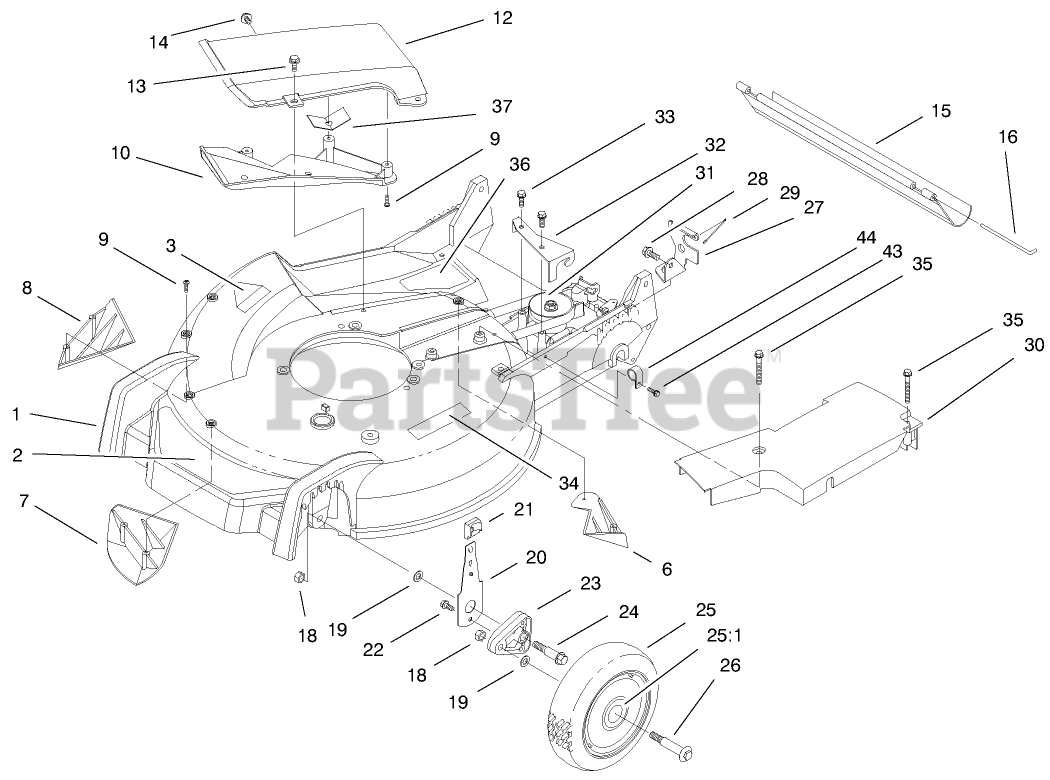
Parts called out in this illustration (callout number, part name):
2	DECAL - DECK
3	DECAL-DANGER
6	KICKER-REAR
7	KICKER-FRONT
8	KICKER-RH
9	SCREW-PPH
10	Deflector-Recycler
11	Guard-Cover
13	SCREW-HWH
14	SCREW AND WASHER ASM
16	ROD-SHIELD
18	NUT-LOCK
19	WASHER
20	FRONT SPRING ARM ASM
21	KNOB-ARM
22	SCREW-HWH
23	ARM-PIVOT, FRONT
24	BOLT-SHOULDER
25	WHEEL AND TIRE ASM
25:1	BUSHING
28	SCREW-HWHTF
29	RETAINER-CABLE
31	GEARCASE ASM
33	SCREW-HWHTF
35	SCREW-HWH
36	DECAL - DANGER
37	Screw-PPH
